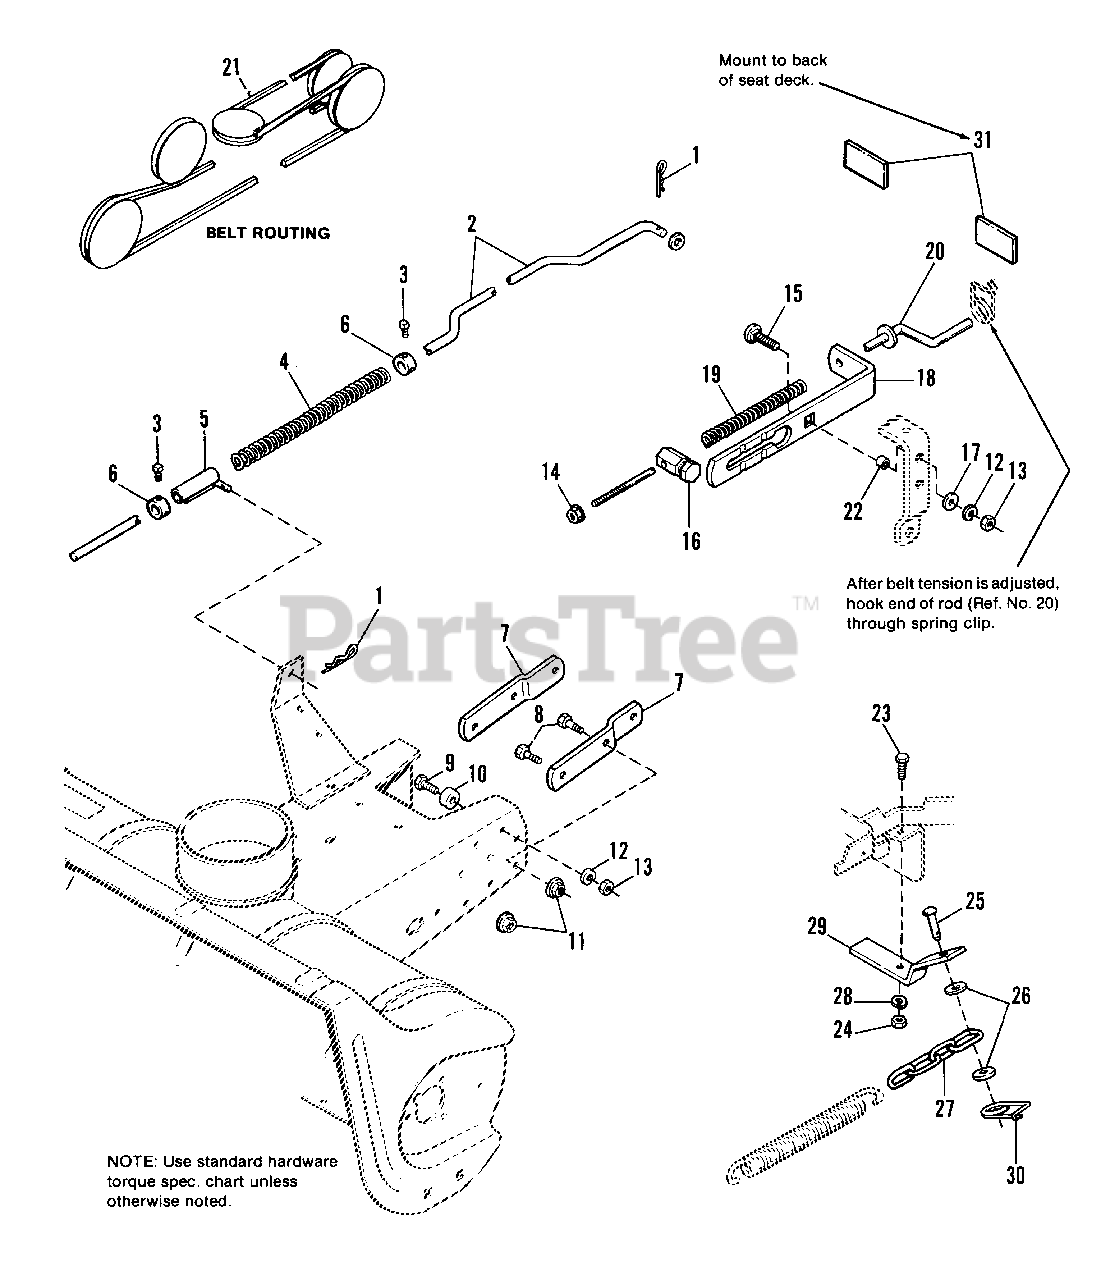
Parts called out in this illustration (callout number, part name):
1	CLIP, Spring
3	SETSCREW, 5/16 x 1/2
5	GUIDE ASSY., Rod
6	COLLAR, Set
7	CLIP, Frame
8	CAPSCREW, Hex, 7/16 x 1
9	CAPSCREW, 3/8-16 x 1-1/4
11	LOCKNUT, Hex, Flange, 7/16-14
12	LOCKWASHER
13	NUT, Hex, Full, 3/8-16
14	LOCKNUT, Hex, Full, 3/8-16
15	CARRIAGE BOLT, 3/8-16 x 1-1/4
17	WASHER, Plain, 5/16
18	GUIDE, Spring
20	ROD ASSY., Adjustment
23	CAPSCREW, Hex, 5/16-18 x 1
24	NUT, Hex, Full, 5/16-18
25	PIN, Hitch
26	WASHER, Plain
27	CHAIN, 4-Link
28	LOCKWASHER, 5/16
29	BRACKET, Spring Anchor
30	CLIP, Spring
